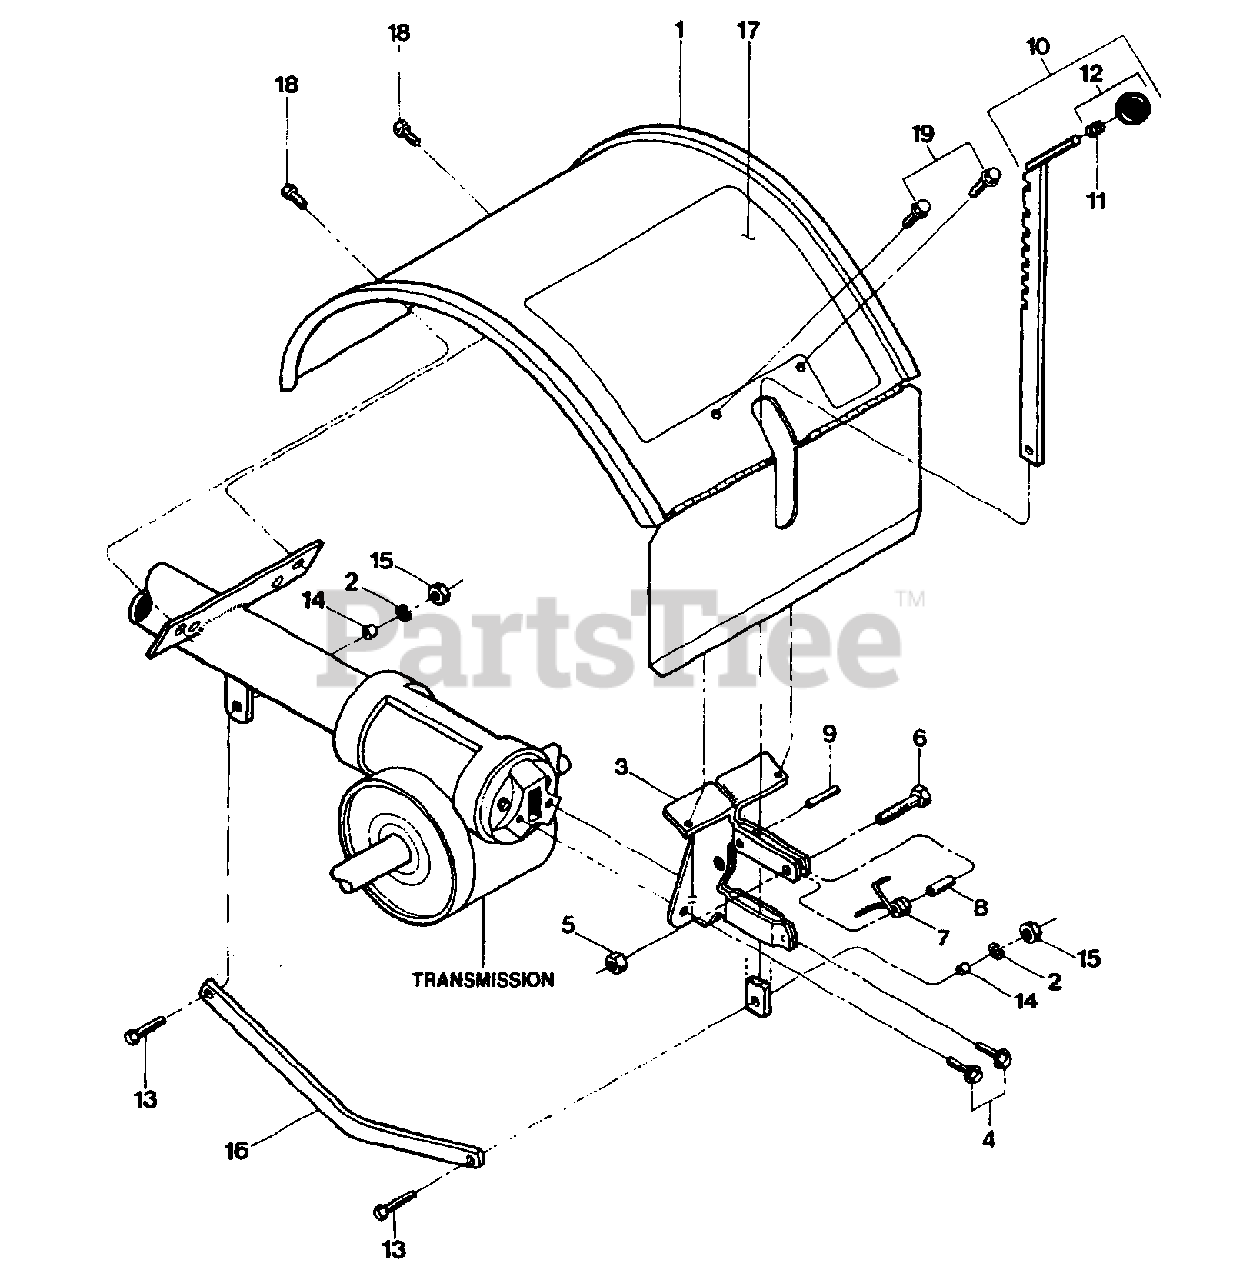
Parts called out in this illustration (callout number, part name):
1	Tine Hood
2	Lockwasher, 3/8
3	Bracket-hood & depth regulator
4	Hex Flange Screw, 5/16-18 x 5/8
5	Hex Locknut, 1/4-20
6	Hex Hd. Screw, 1/4-20 x 1
7	Spring
9	Roll Pin (spiral), 1/4 x 1
10	Depth Adjustment Bar Assembly
11	Retaining Ring (tolerance ring)
12	Knob, Depth Regulator
13	Hex Hd. Screw, 3/8-16 x 1-1/4
14	Bushing, Drag Bar
15	Hex Nut, 3/8-16
16	Drag Bar
17	Decal, operating instructions
18	Hex Hd. Screw, self-tapping, 5/16-18 x 1/2
19	Hex Flange Screw, self-tapping, 1 /4-20 x 1/2
